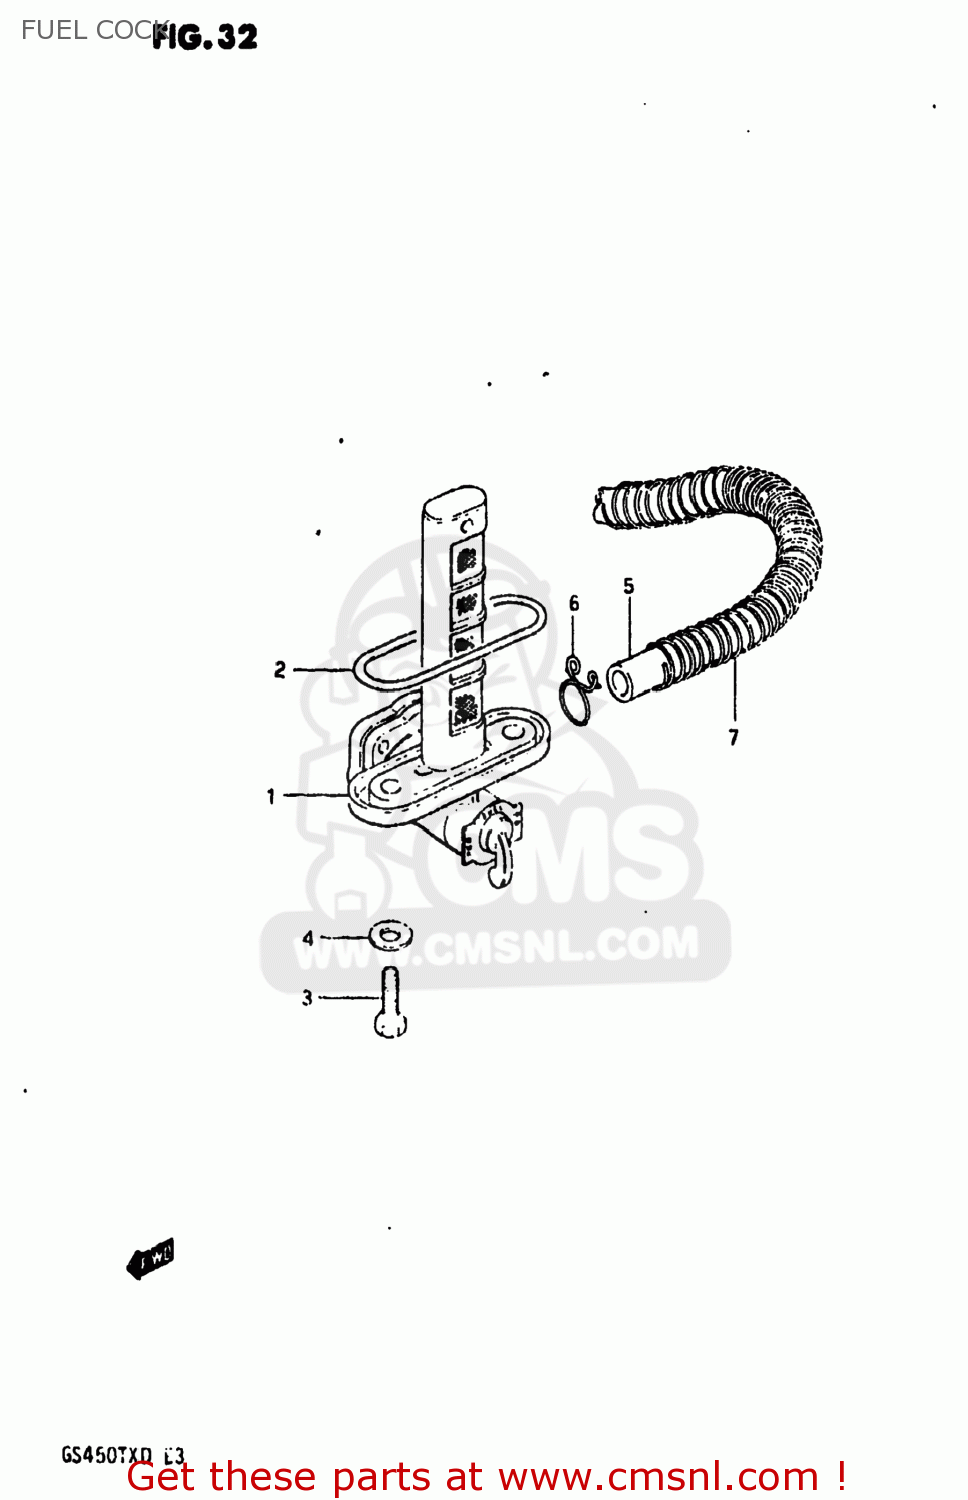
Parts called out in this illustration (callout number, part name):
1	COCK ASSEMBLY,FUEL
2	O RING
3	BOLT(6X20)
4	GASKET
5	HOSE
6	CLIP
7	SPRING
